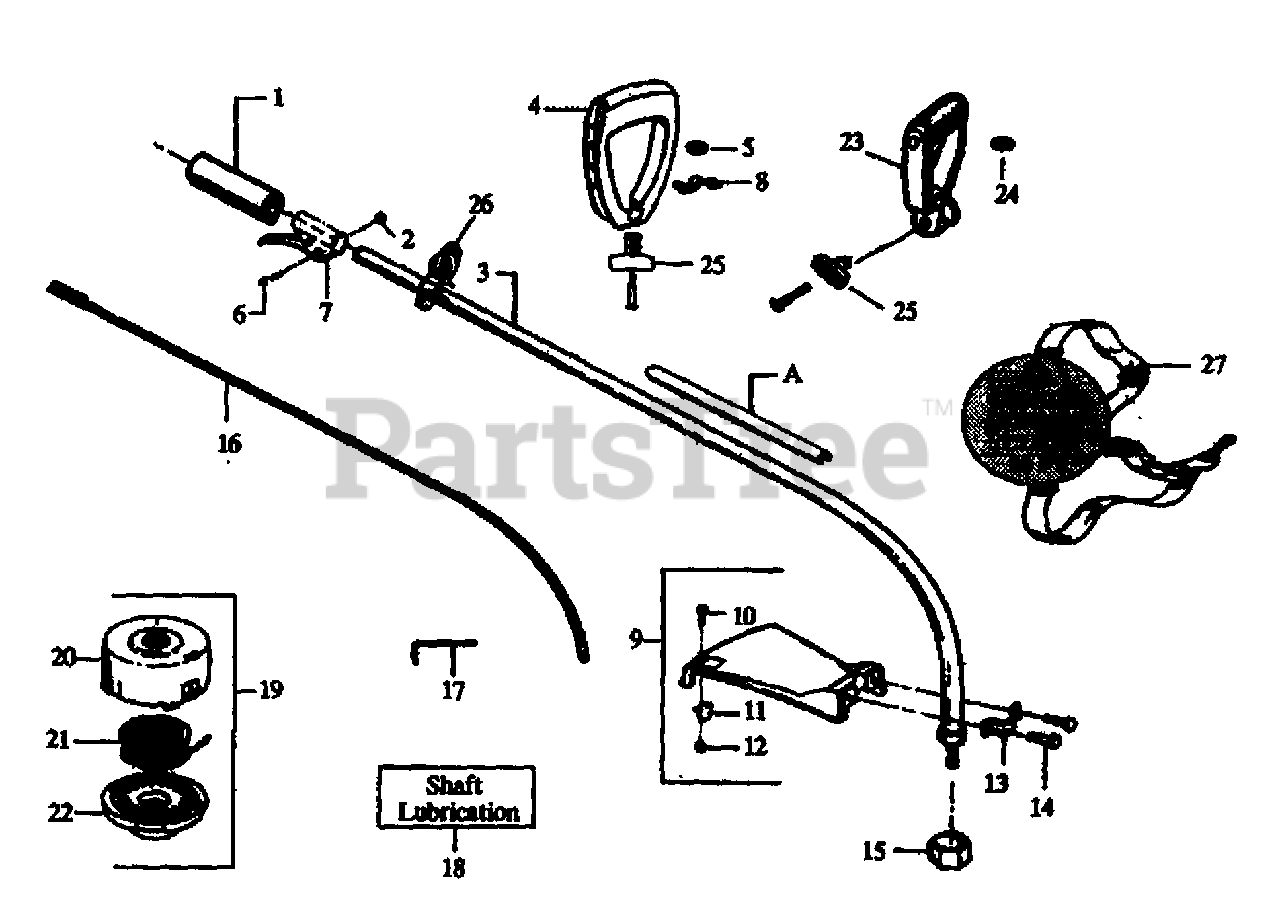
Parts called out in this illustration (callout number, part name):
1	Grip
3	Drive Shaft Housing
4	Handle Ass'y.
7	Throttle Housing Ass'y.
9	Shield Kit Ass'y.
11	Line Limiter
12	Locknut
13	Shield Bracket
14	Screw
17	Hex Wrench (5/32)
18	Shaft Lubrication
19	Cutting Head Ass'y.
20	Hub Ass'y.
21	Spool w/Line
25	"T" Handle Ass'y.
26	Clamp Harness Ass'y.
27	Shoulder Strap
A	Shaft Warning Decal
